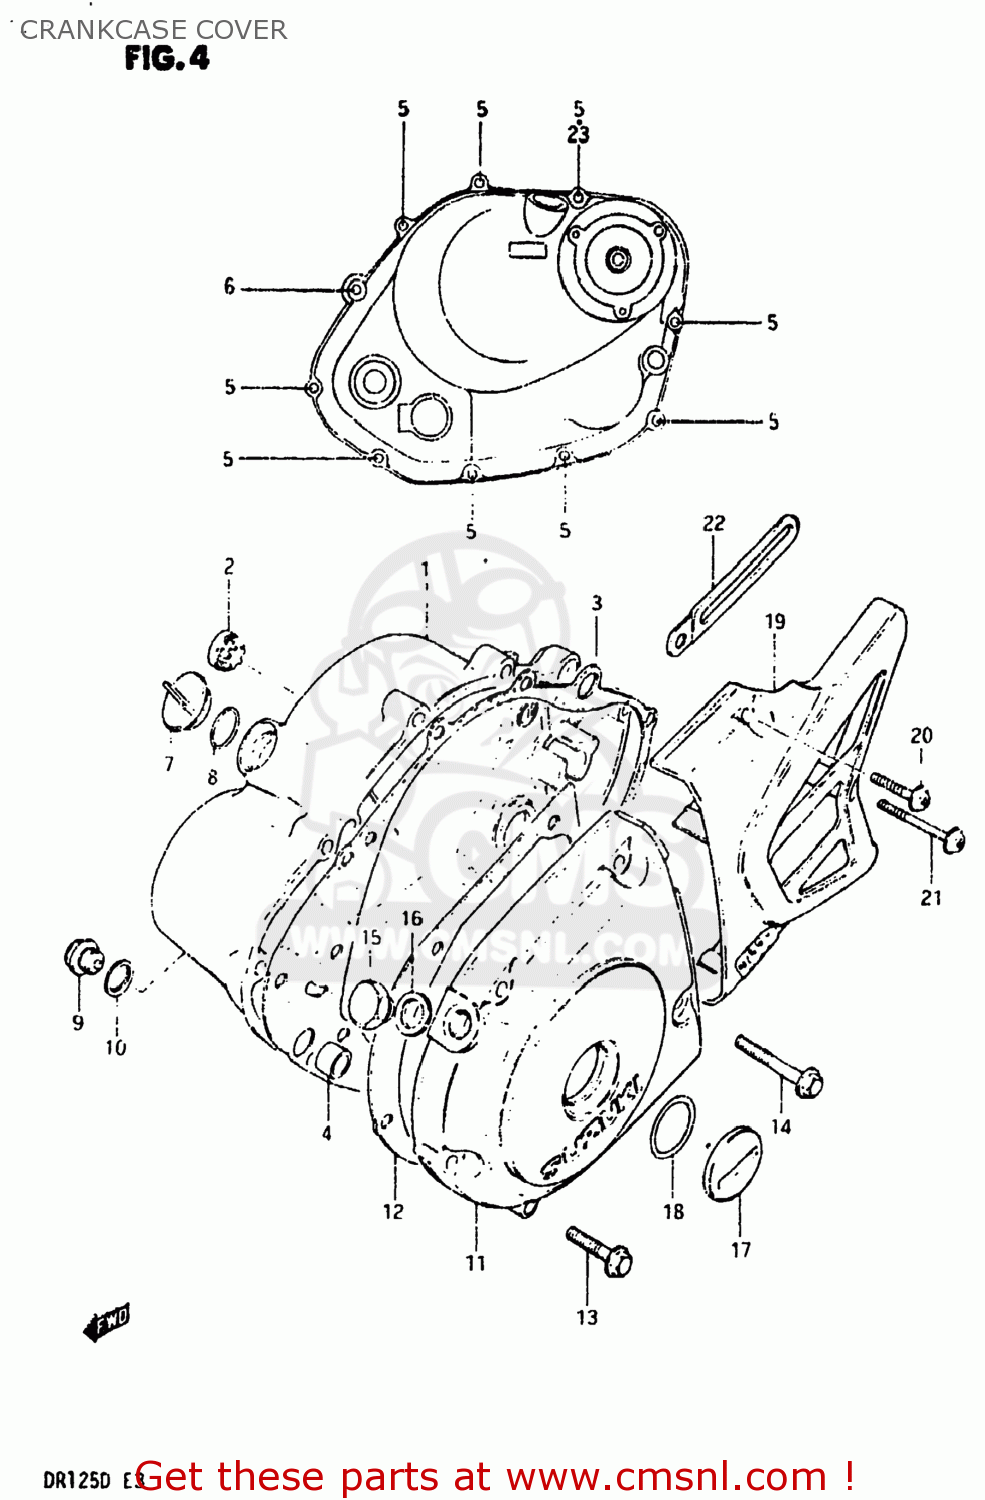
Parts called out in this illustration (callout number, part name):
1	COVER,CLUTCH
2	LENS,OIL LEVEL CHECK
3	GASKET,CLUTCH COVER (MCA)
4	PIN
5	BOLT (6*30)
6	BOLT (6X45)
7	PLUG
8	O RING(D:3.1,ID:16.8)
9	PLUG (14X12)
10	GASKET(14X19.2X2) (NAS)
11	COVER,MAGNETO
12	GASKET,MAGNETO COVER (MCA)
13	BOLT (6*30)
14	BOLT (6X40)
15	PLUG(12X9)
16	GASKET(12.1X16.2X3.7) (NAS)
17	PLUG
18	O RING(D:3.1,ID:22.7)
19	COVER,SPROCKET
20	SCREW
21	SCREW
22	CLAMP
23	GASKET (NAS)
